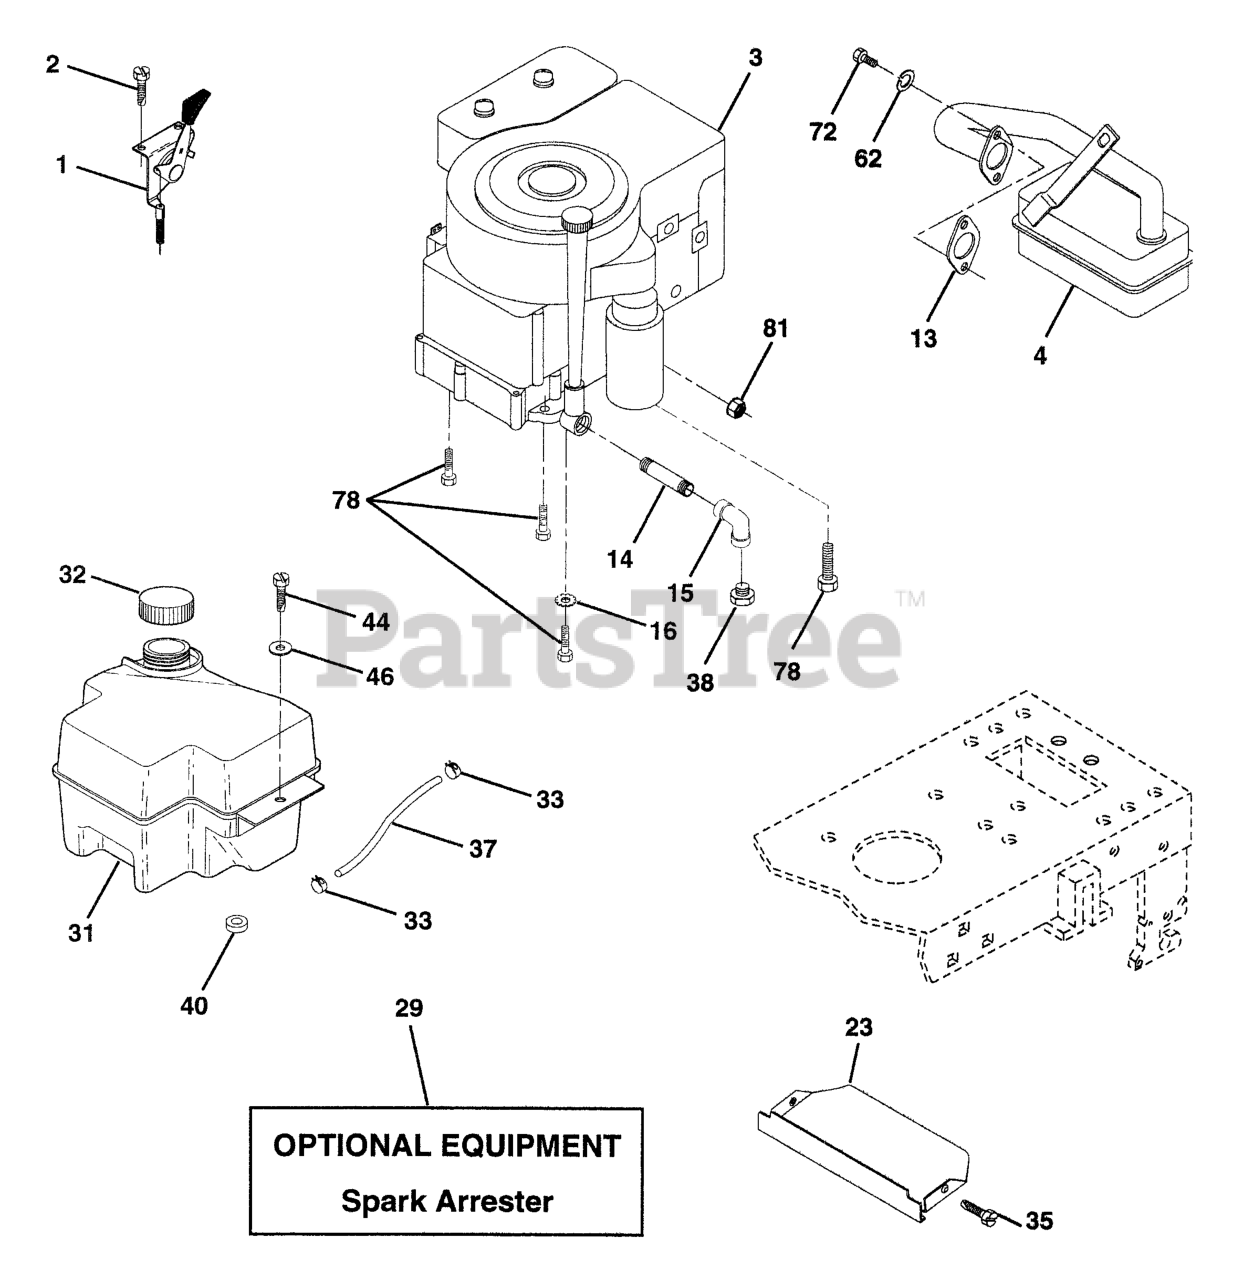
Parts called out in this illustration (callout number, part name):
1	CHOKE CONTROL
2	SCREW LT
4	MUFFLER.SINGLE.B&S.10-12HP
13	GASKET.ENG.1.313 ID.TIN PLATED
14	Nipple Pipe 3/8 Npt X 3"
15	ELBOW
16	LOCKWASHER
29	KIT.SPARK ARRESTOR 794945 B&S
31	FUEL TANK
32	FUEL CAP
33	HOSE CLAMP
35	SCREW.THDROL.5/16-18X3/4.TTY
37	LINE.FUEL.20
38	Plug Oil Drain
40	BUSHING.SNAP.NYL.BLK.
44	SCREW HEX CRT
46	WASHER
62	WASHER.LOCK.HVY.HLCL.SPR.5/16
72	SCREW
78	SCREW
81	NUT FLANGE 1/4-20 STARTER NUT
